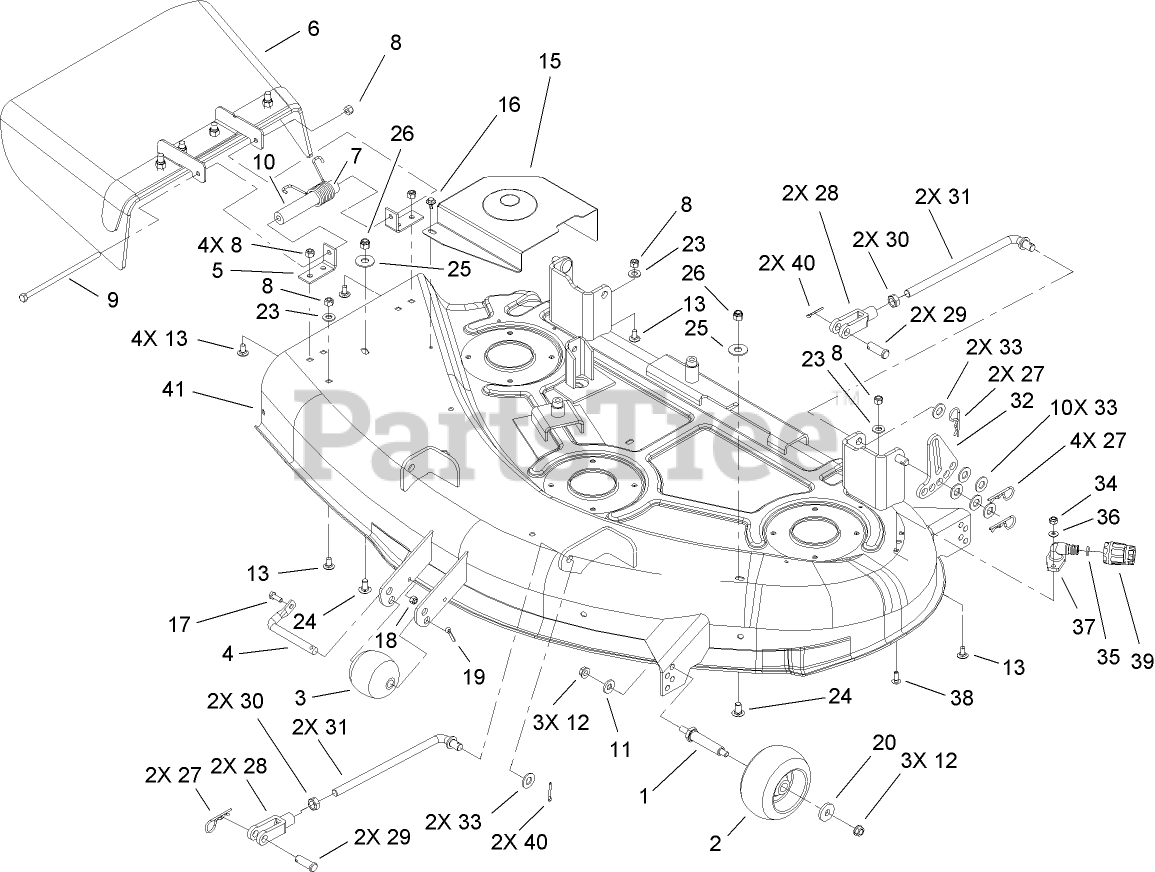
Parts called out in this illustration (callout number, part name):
2	ROLLER-SCALP, ANTI
3	ROLLER
4	SHAFT-ROLLER
5	BRACKET-PIVOT, DEFLECTOR
6	DEFLECTOR ASM
7	SPRING-TORSION
8	NUT-LOCK, NI
9	BOLT-HH
10	SPACER-DEFLECTOR
11	WASHER-BELLEVILLE
12	NUT-HHF, WHIZ
13	SCREW-CARR
15	COVER-BELT, RH
16	SCREW-HHFTF
17	SCREW-HH
18	NUT-LOCK, NI
19	PIN-COTTER
20	WASHER
23	WASHER-FLAT
24	SCREW-CARR
25	WASHER-FLAT
26	NUT-LOCK, NI
27	PIN-COTTER
28	CLEVIS
29	PIN-CLEVIS
30	NUT-JAM
32	LINK-HOC, ADJUSTING
33	WASHER-FLAT
34	NUT-LOCK, NI
35	O-RING
36	WASHER-FLAT
38	BOLT-CARR
39	CONNECTOR-HOSE
40	PIN-COTTER
41	44 INCH DECK ASM
